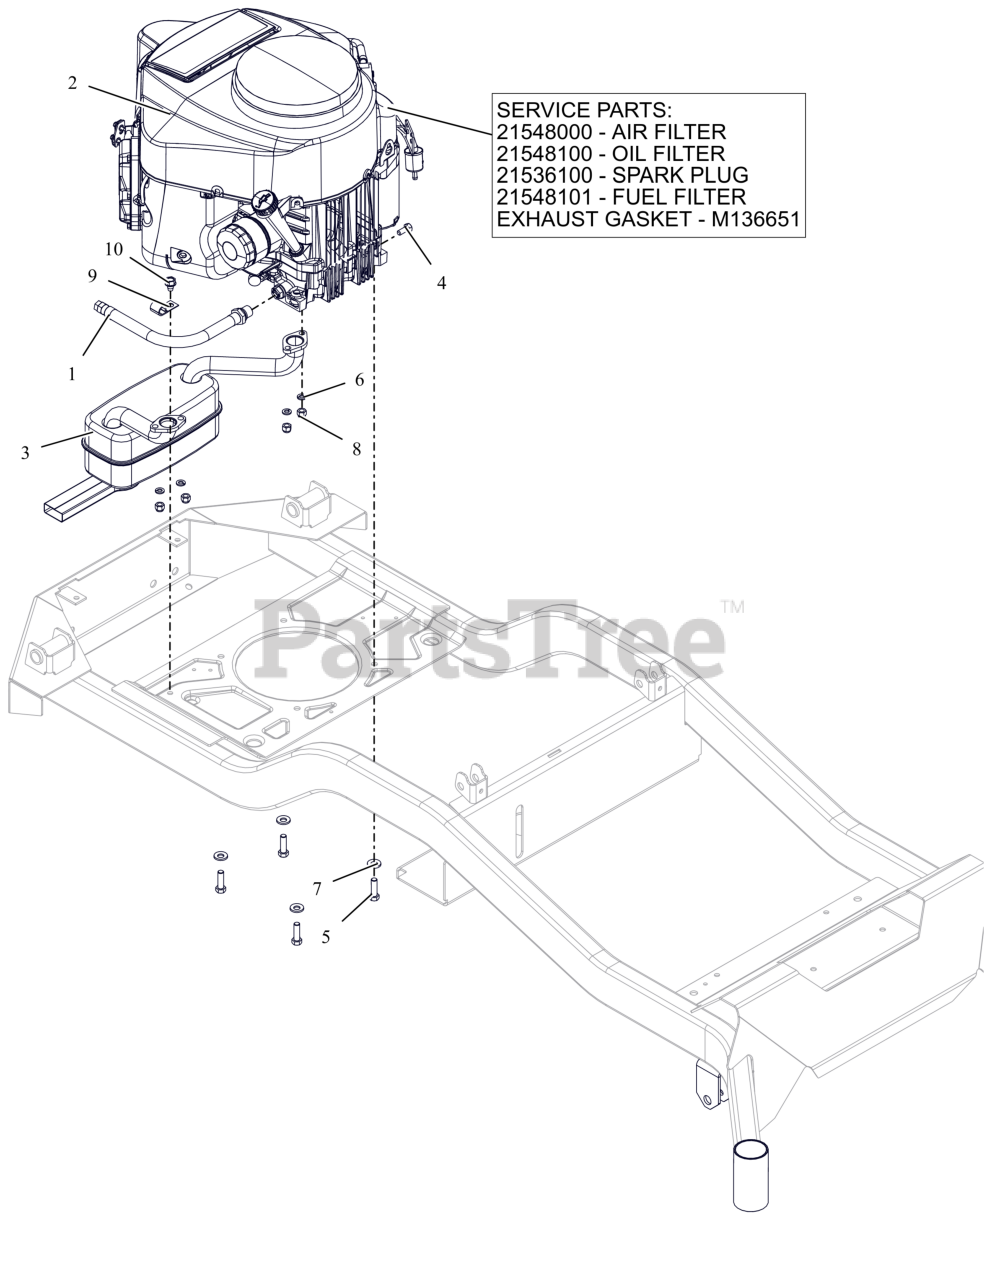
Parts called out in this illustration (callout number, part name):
1	HOSE, OIL DRAIN
2	ENGINE, KAWASAKI FR691 23HP
2	AIR FILTER, KAWASAKI FR
2	OIL FILTER, KAWASAKI FR
2	PLUG, SPARK
2	FUEL FILTER-KAWASAKI FR
2	GASKET, MUFFLER #
3	MUFFLER, KAWASAKI
4	BLT, HEX M8-1.25X20 G8.8 ZCC
5	BLT, HEX .38-16X1.25 G5 ZCC NT
6	WSHR,LK-REG .312X.078 ZCC
7	WASHER, 3/8" SPRING DISC
8	NUT, LK-CTR-JAM M8-1.25 GR8.8 ZC120
9	J-CLAMP
10	SCR,TAP .375-16X.50 HWH TR ZCC
